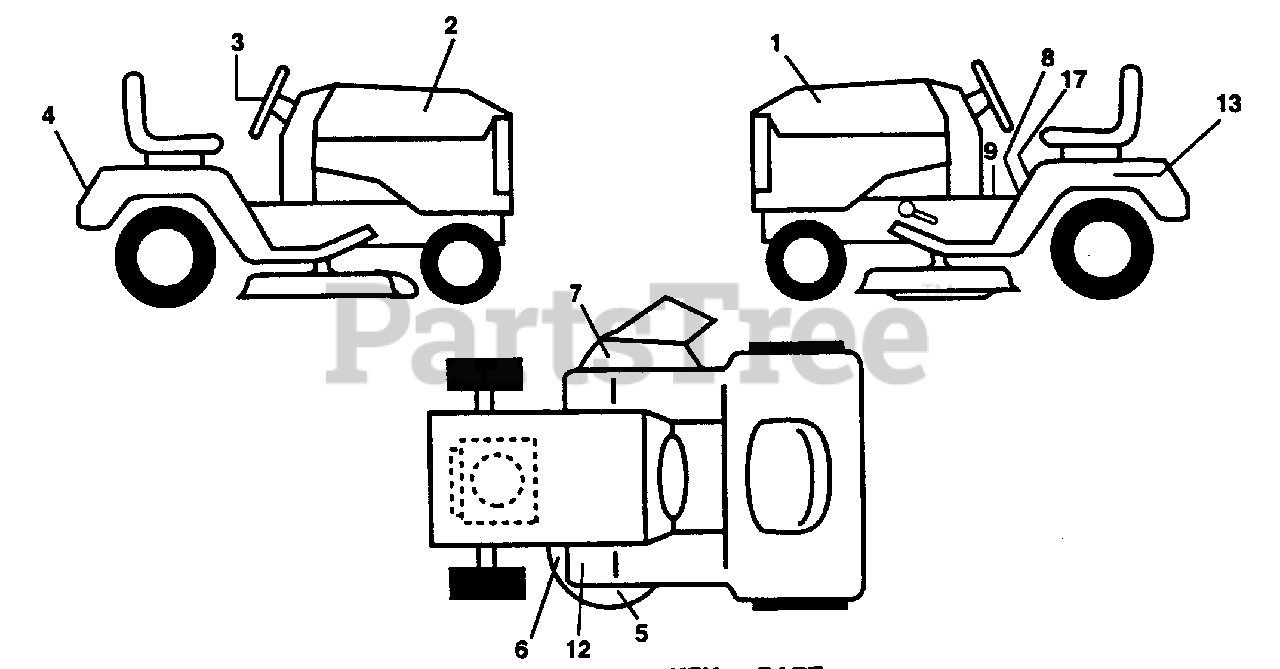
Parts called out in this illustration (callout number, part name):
1	Decal Hood Slope LH
2	Decal Hood Slope RH
3	Decal Panel Side LH
4	Decal Fender (AYP part number)
5	Decal Engine 12.5 HP B&S ICQ (AYP part number)
6	Decal, V-Belt Sch 38"/42" LT (AYP part number)
7	Decal Warning MULT-LANGUAGE (AYP part number)
8	Decal Dash Instructions Operating Eng/Fr (AYP part number)
9	Decal Sdl Cold Start Hydo Eng/Fr (AYP part number)
12	Decal Clutch/brake Eng/Fr/Ger/Du (AYP part number)
13	Decal Caution Battery Fr/Ger (AYP part number)
17	Decal Caution Fender Eng/Fr (AYP part number)
